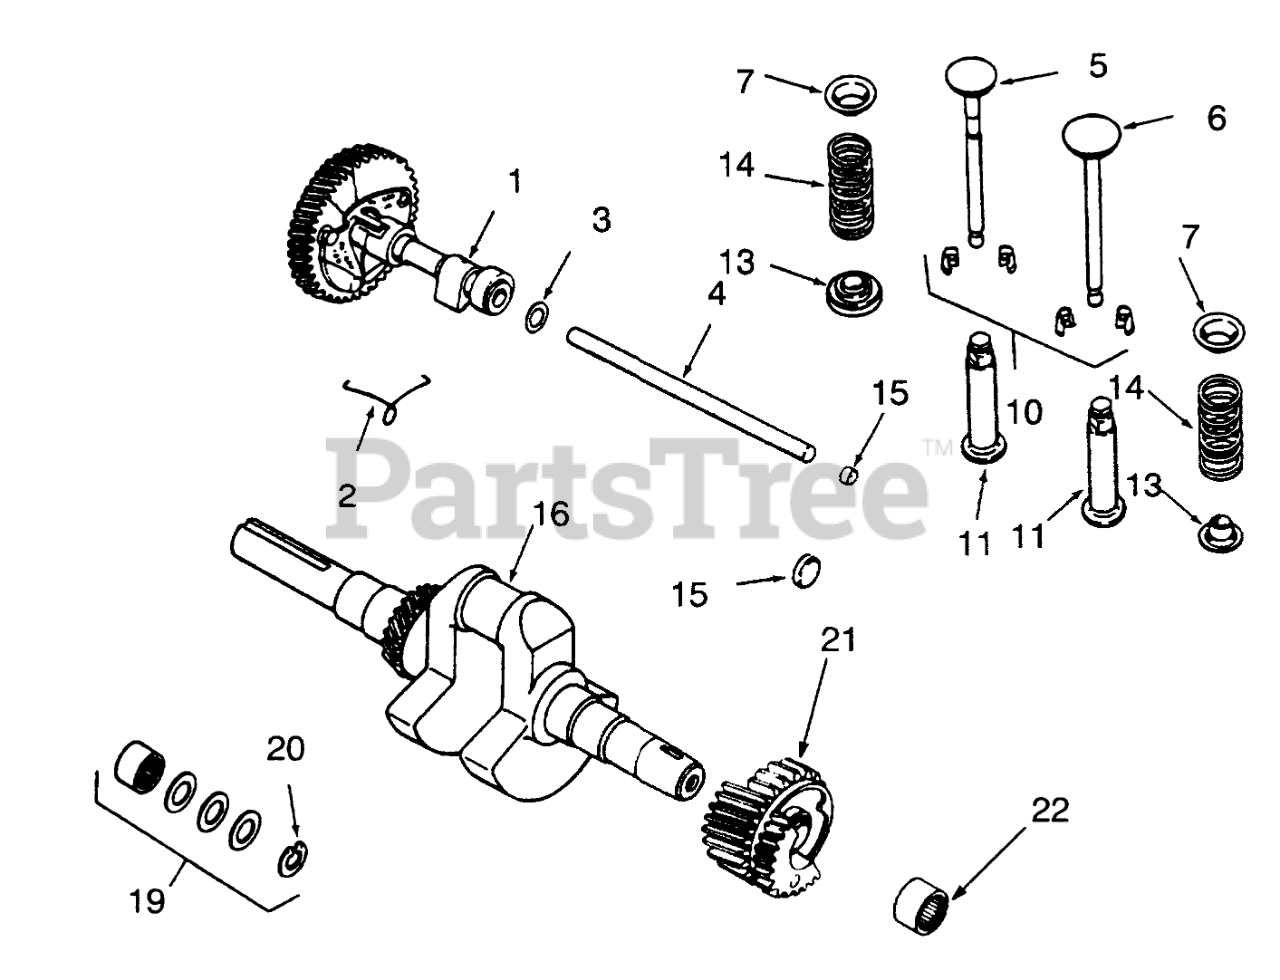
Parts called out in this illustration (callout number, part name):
1	Camshaft Assy (Incl. Ref.# 2)
2	Spring
3	Spacer .005
4	Camshaft Pin
5	Valve-Exhaust
6	Valve-Intake
7	UpperSpring Retainer
10	Kit-Retainer
11	Tappet
13	Rotator-Valve
14	Spring
16	Kit-Crankshaft (Includes Flywheel Hdwr.)
19	Kit-Spacer (Incl. Ref.#20)
20	Retainer
21	Gear Assembly (Incl. Ref. #22)
22	Bearing-Needle
